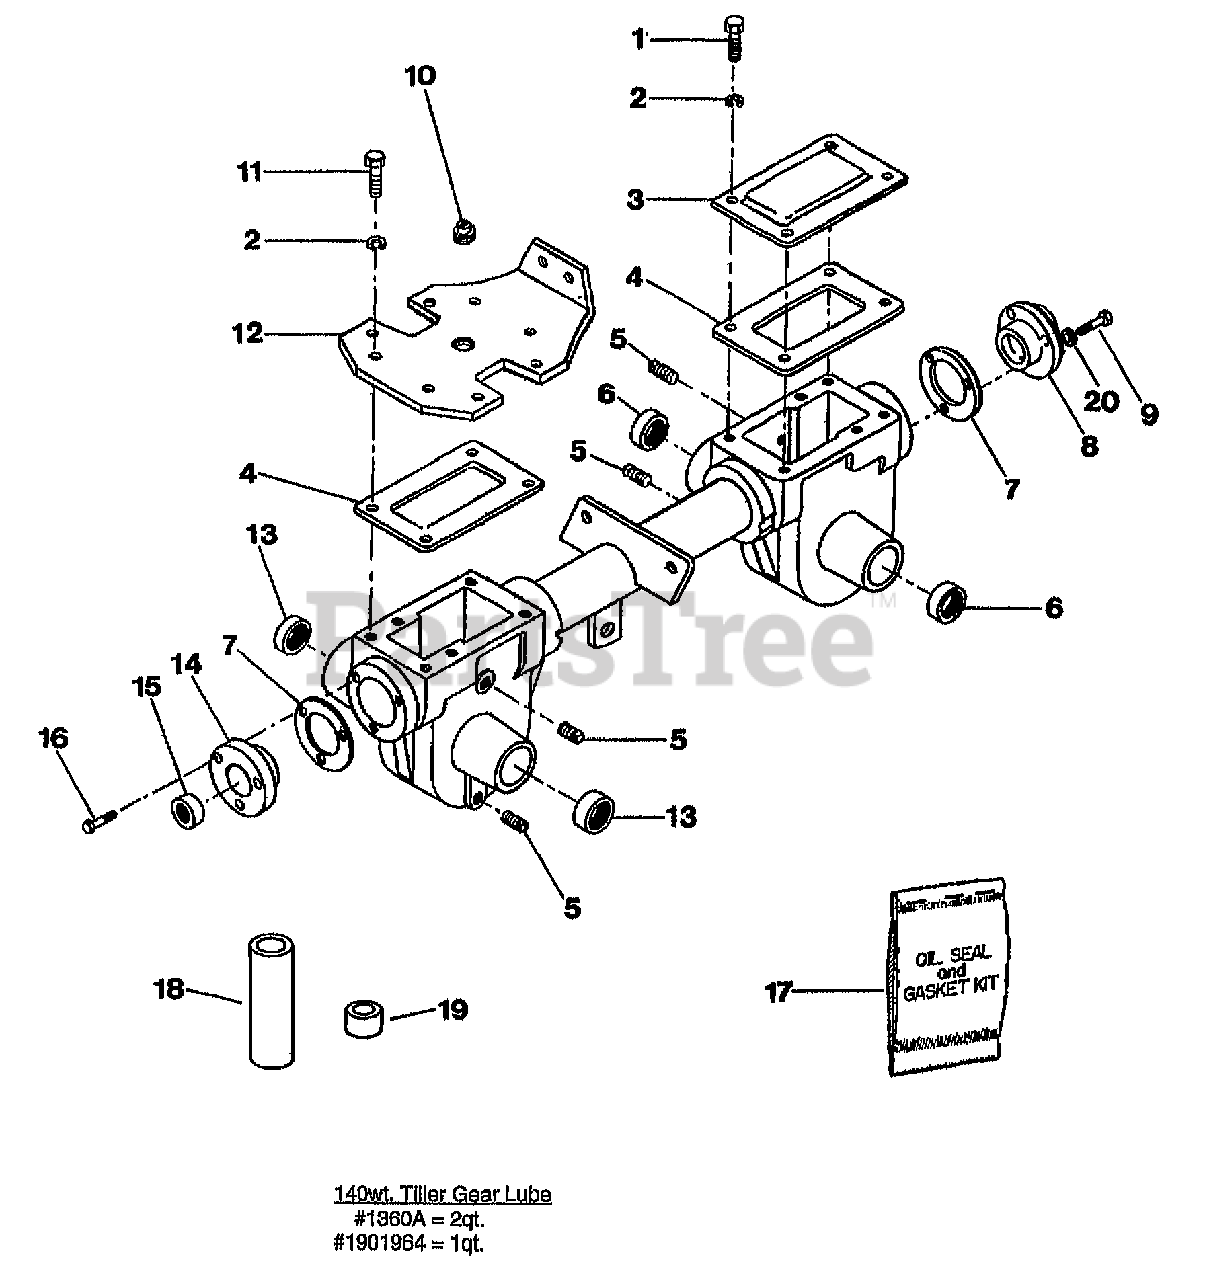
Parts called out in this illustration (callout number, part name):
1	SCR-HH 5/16-18X.5 GD5 YEL (For Tiller Housing Cover)
2	WASHER-LK .312 ZP
3	CVR-TRANS REAR PNT (Tiller Housing)
4	GASKET-GEAR HSG (Transmission & Tiller Housing Cover)
5	PLUG-PIPE 1/4 NPT (Oil level & Drain)
6	SEAL-OIL TRIPLE LIP (Tiller Housing)
7	GASKET-BRG COVER (Front & Rear)
8	CAP-REAR #1115
9	SCR-HFLK 1/4-20X.875 (For Rear Bearing Cap)
10	PLUG-OIL FILL 3/4-10
11	SCR-HHC 5/16-18X.75 GR 5 ZP (For Transmission Cover)
12	COVER-TRANS MACH
13	SEAL-OIL WHEELSHAFT
14	COVER-FRONT
15	SEAL-PINION SHAFT PT/85030/00
16	SCR-HFLK 1/4-20X.75 G5 ZP (For Front Bearing Cap)
17	SEAL & GASKET SET-JR (Inc. 2 #7, 2 #4, 2 #6, 1 #15)
18	DRIVER-PLASTIC
19	SEAL-DRIVER PILOT (Used with #18)
20	WASHER-.36X.25X.03 NYLON
